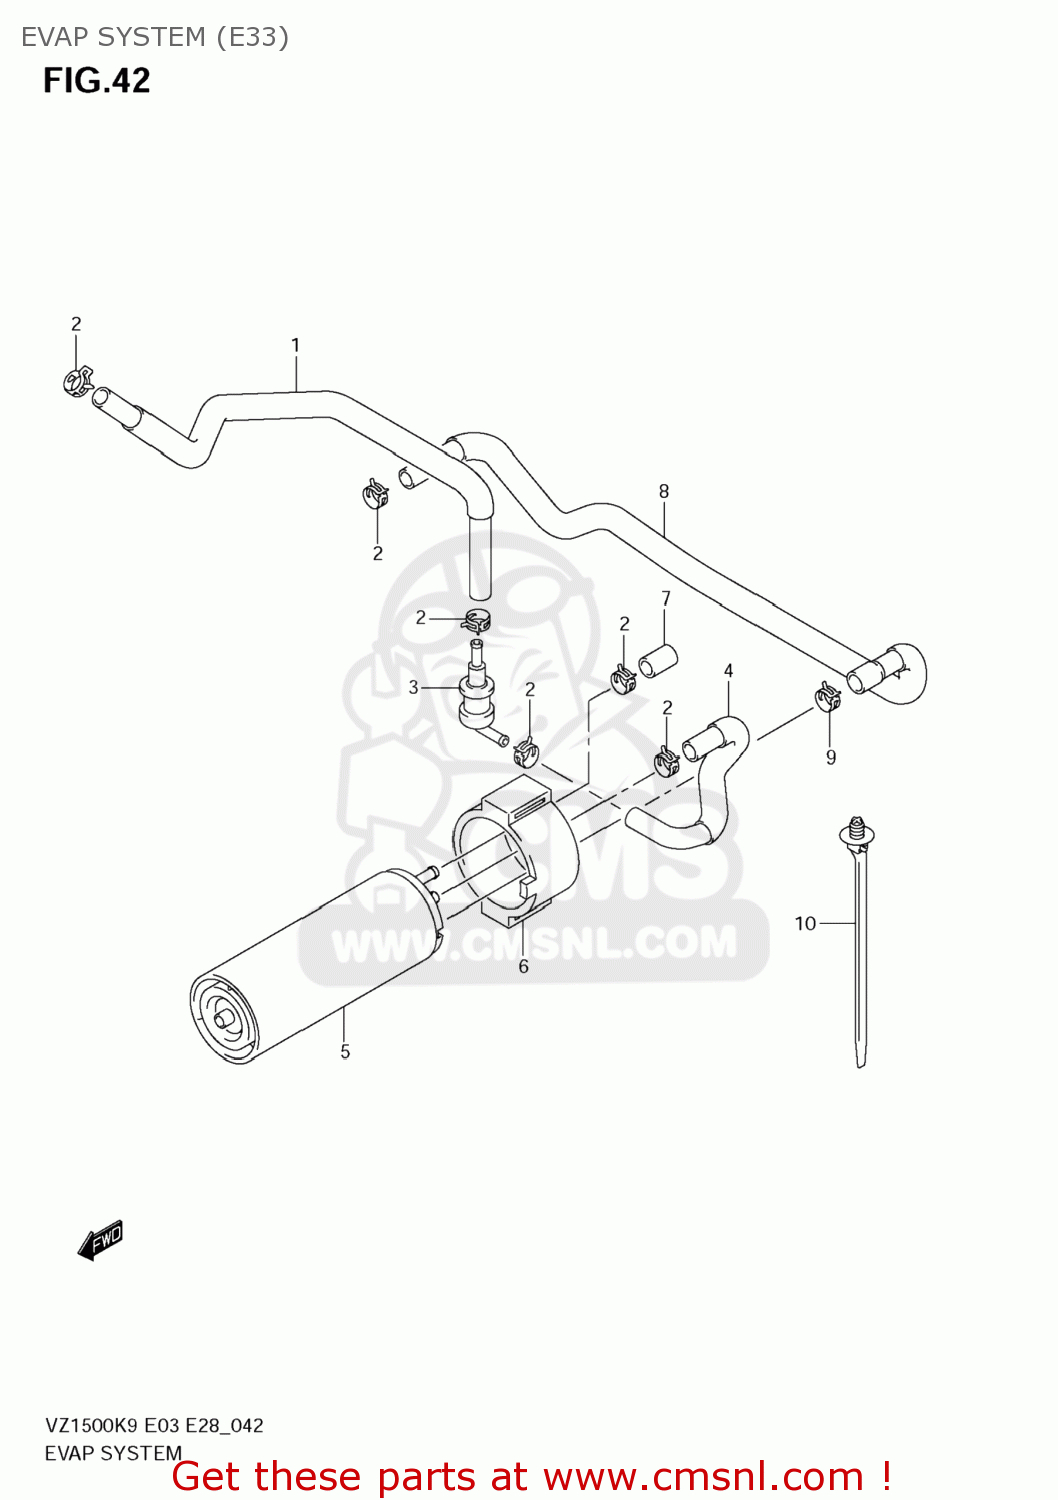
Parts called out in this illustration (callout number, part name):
1	HOSE,TANK & BREATHER VALVE
2	CLIP
3	VALVE,FUEL TANK BREATHER
4	HOSE,BREATHER VALVE & CANISTER
5	CANISTER ASSY,CHARCOAL
6	CUSHION,CANISTER
7	CAP,OD:11.5
8	HOSE,CSTR PURGE
9	CLIP
10	CLAMP(L:154)
